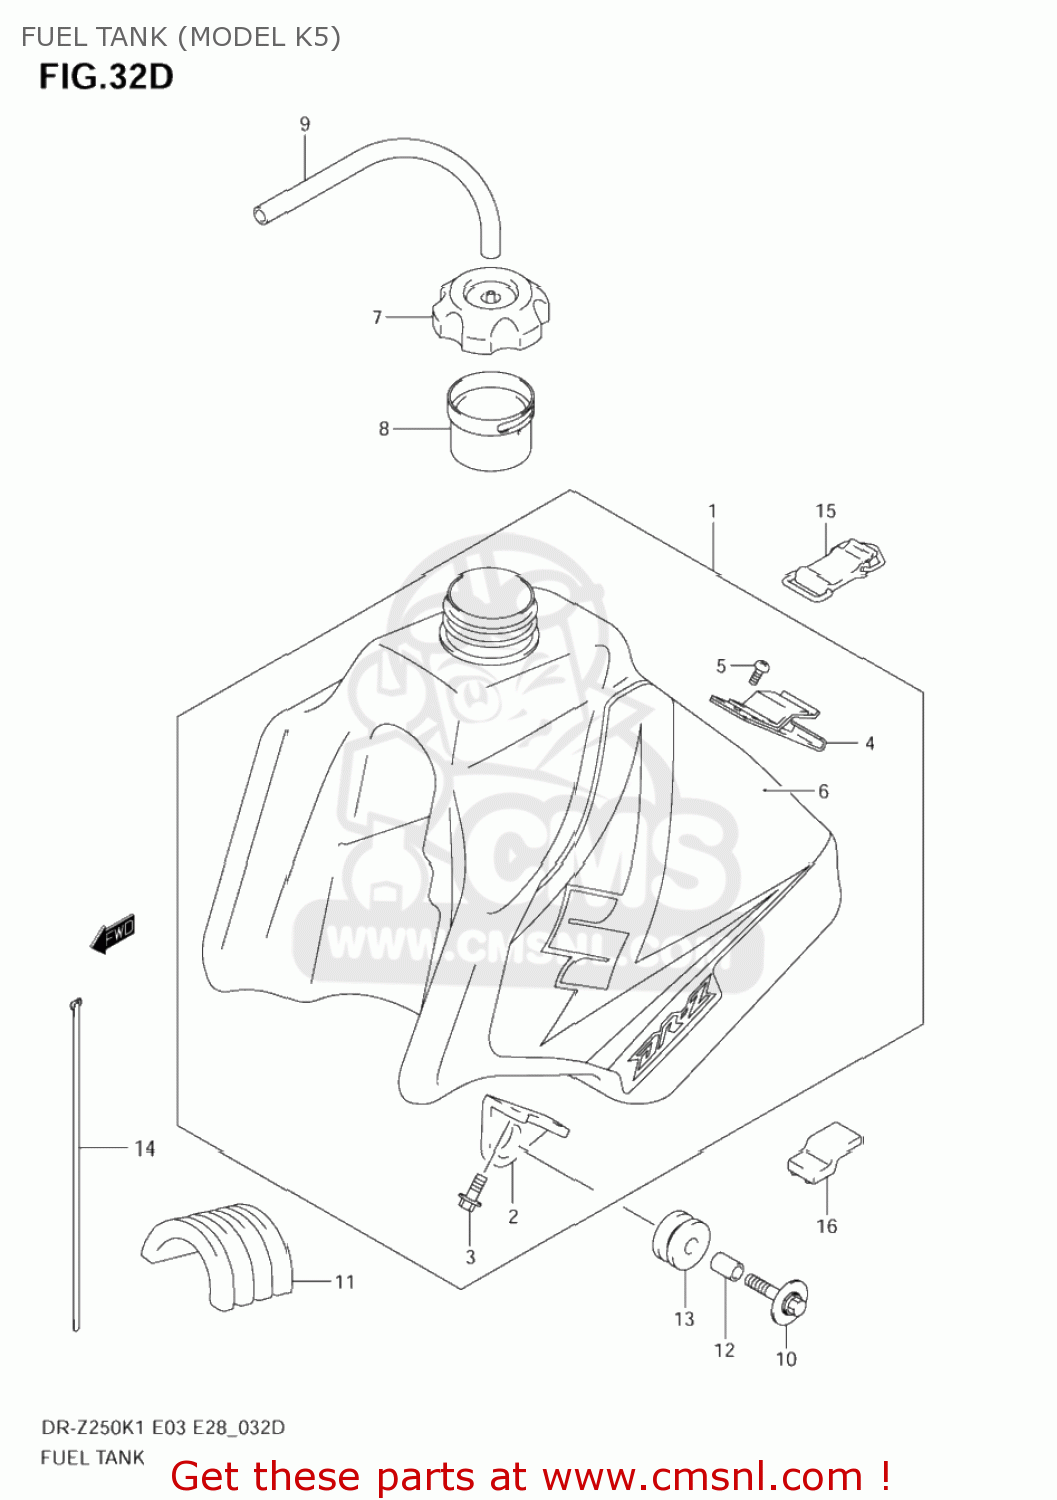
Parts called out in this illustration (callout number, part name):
1	TANK ASSY,FUEL(YELLOW)
2	BRACKET,FUEL TANK FR
3	BOLT
4	BRACKET,FUEL TANK RR
5	SCREW 6X12
6	TAPE SET,FUEL TANK(YELLOW)
7	CAP ASSY,FUEL TANK FILLER
8	TUBE,FILLER INLET
9	HOSE(5X8.2X600)
10	BOLT(6X30)
11	CUSHION,FUEL TANK
12	SPACER(6.5X9X13.5)
13	CUSHION,MUFFLER
14	CLAMP(L:300)
15	BAND,FUEL TANK RR
16	CUSHION,FUEL TANK
